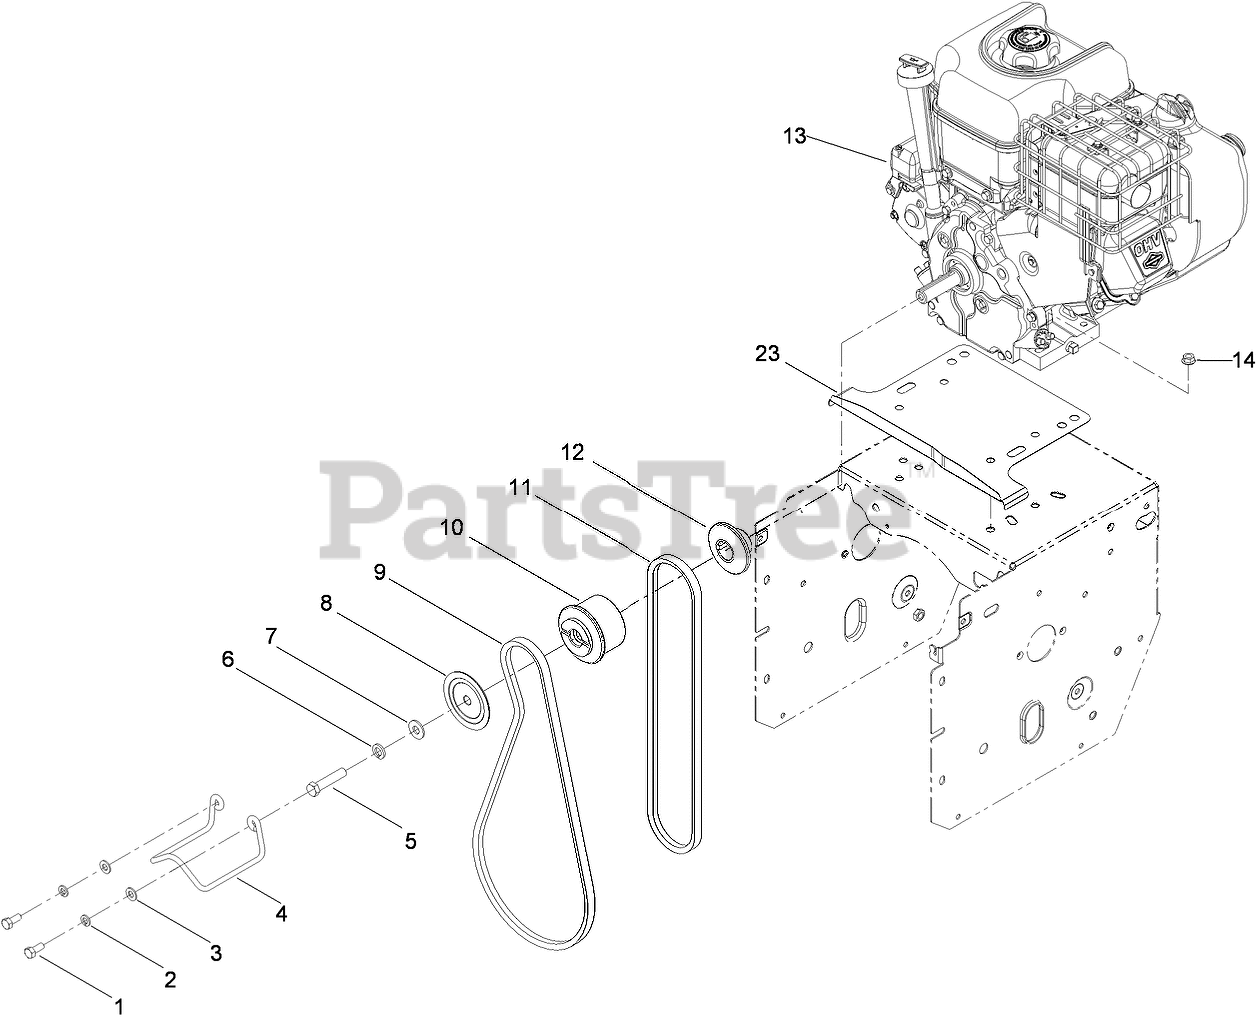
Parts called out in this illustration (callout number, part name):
1	SCREW-HH
2	WASHER-LOCK
3	WASHER-PLAIN
4	GUIDE-BELT
5	SCREW-HH
6	WASHER-LOCK
7	WASHER-FLAT
8	SHEAVE-HALF, IMPELLER
9	BELT-V
10	PULLEY-ENGINE, CENTER
11	V BELT-TRACTION
12	SHEAVE-HALF, TRACTION
14	NUT-HF
23	SHIELD-DRIVE
